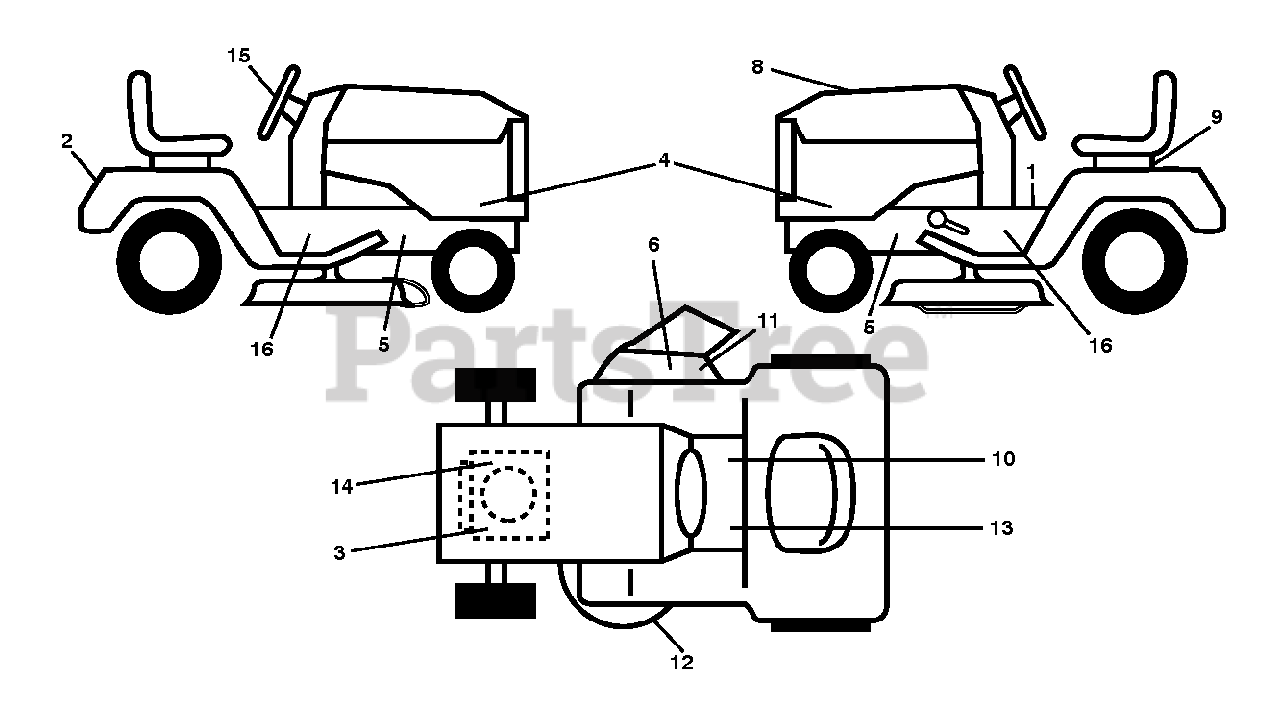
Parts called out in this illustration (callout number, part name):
4	DECAL.SDPNL.LT2313.BRIGGS.JONS
6	DECAL, DECK DEFLECTOR, WARNING
8	DECAL.RPL.BSM21.PB.TLW.38.PMST
9	DECAL BTRY SYMBOLS
12	DECAL.DECK.SCH.3638
14	DECAL.ENG.BS.3125SER.PB.279738
